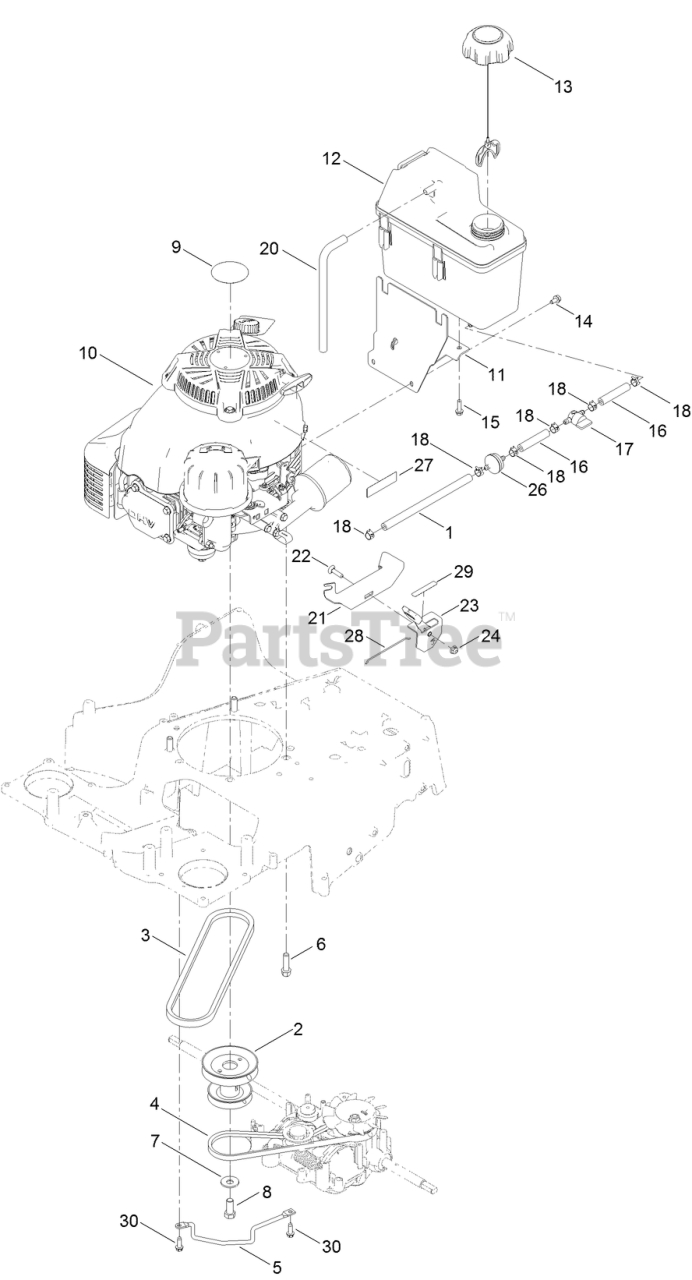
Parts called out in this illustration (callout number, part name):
1	HOSE-FUEL
2	PULLEY-ENGINE
3	V-BELT
4	BELT-V
5	ROD-GUIDE, BELT
6	SCREW-TAPTITE
7	WASHER-BELLEVILLE
8	SCREW-HH
10	ENGINE-FJ180V KAW BBC
11	MOUNT-TANK
12	TANK-FUEL
13	CAP-FUEL
14	SCREW-HWH
15	SCREW-HWH
16	HOSE-FUEL
17	VALVE-FUEL
18	CLAMP-HOSE
20	HOSE-VENT, CANISTER
21	BRACKET-MOUNT, THROTTLE
22	SCREW-CARR
23	CONTROL-THROTTLE
24	NUT-HF
26	FILTER-FUEL
27	DECAL-WARNING, ENGINE
28	WIRE-CONTROL
29	DECAL-THROTTLE, CHOKE
30	SCREW-HWHTF
